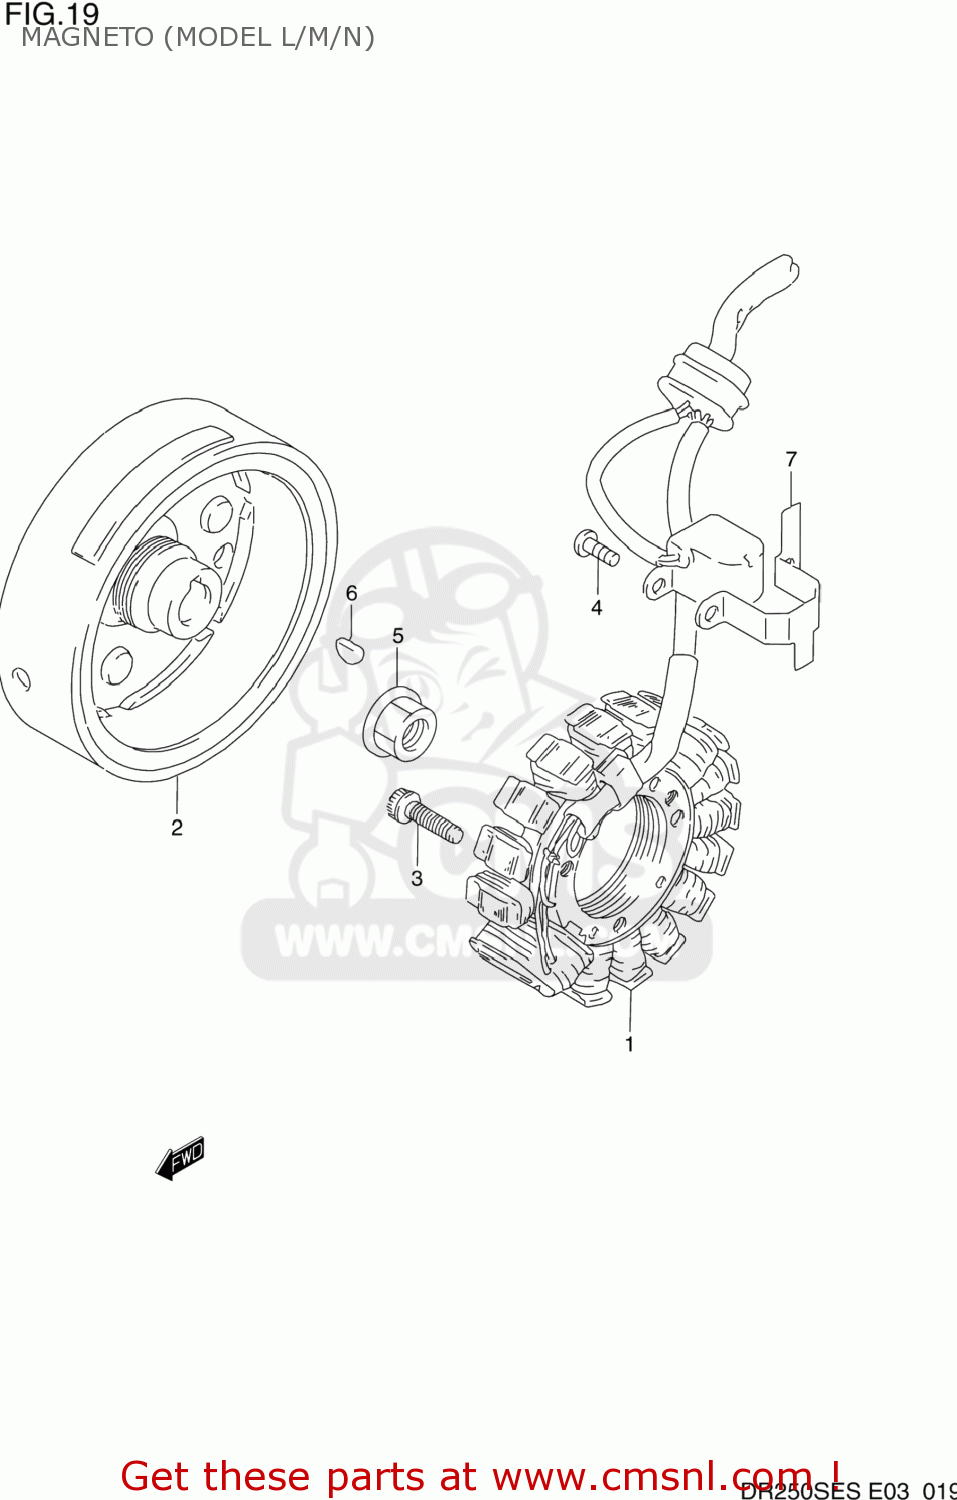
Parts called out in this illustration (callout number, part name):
1	STARTER ASSY
2	ROTOR ASSEMBLY
3	BOLT
4	SCREW
5	NUT
6	KEY 4MM
7	CLAMP,MAGNETO LEAD WIRE
